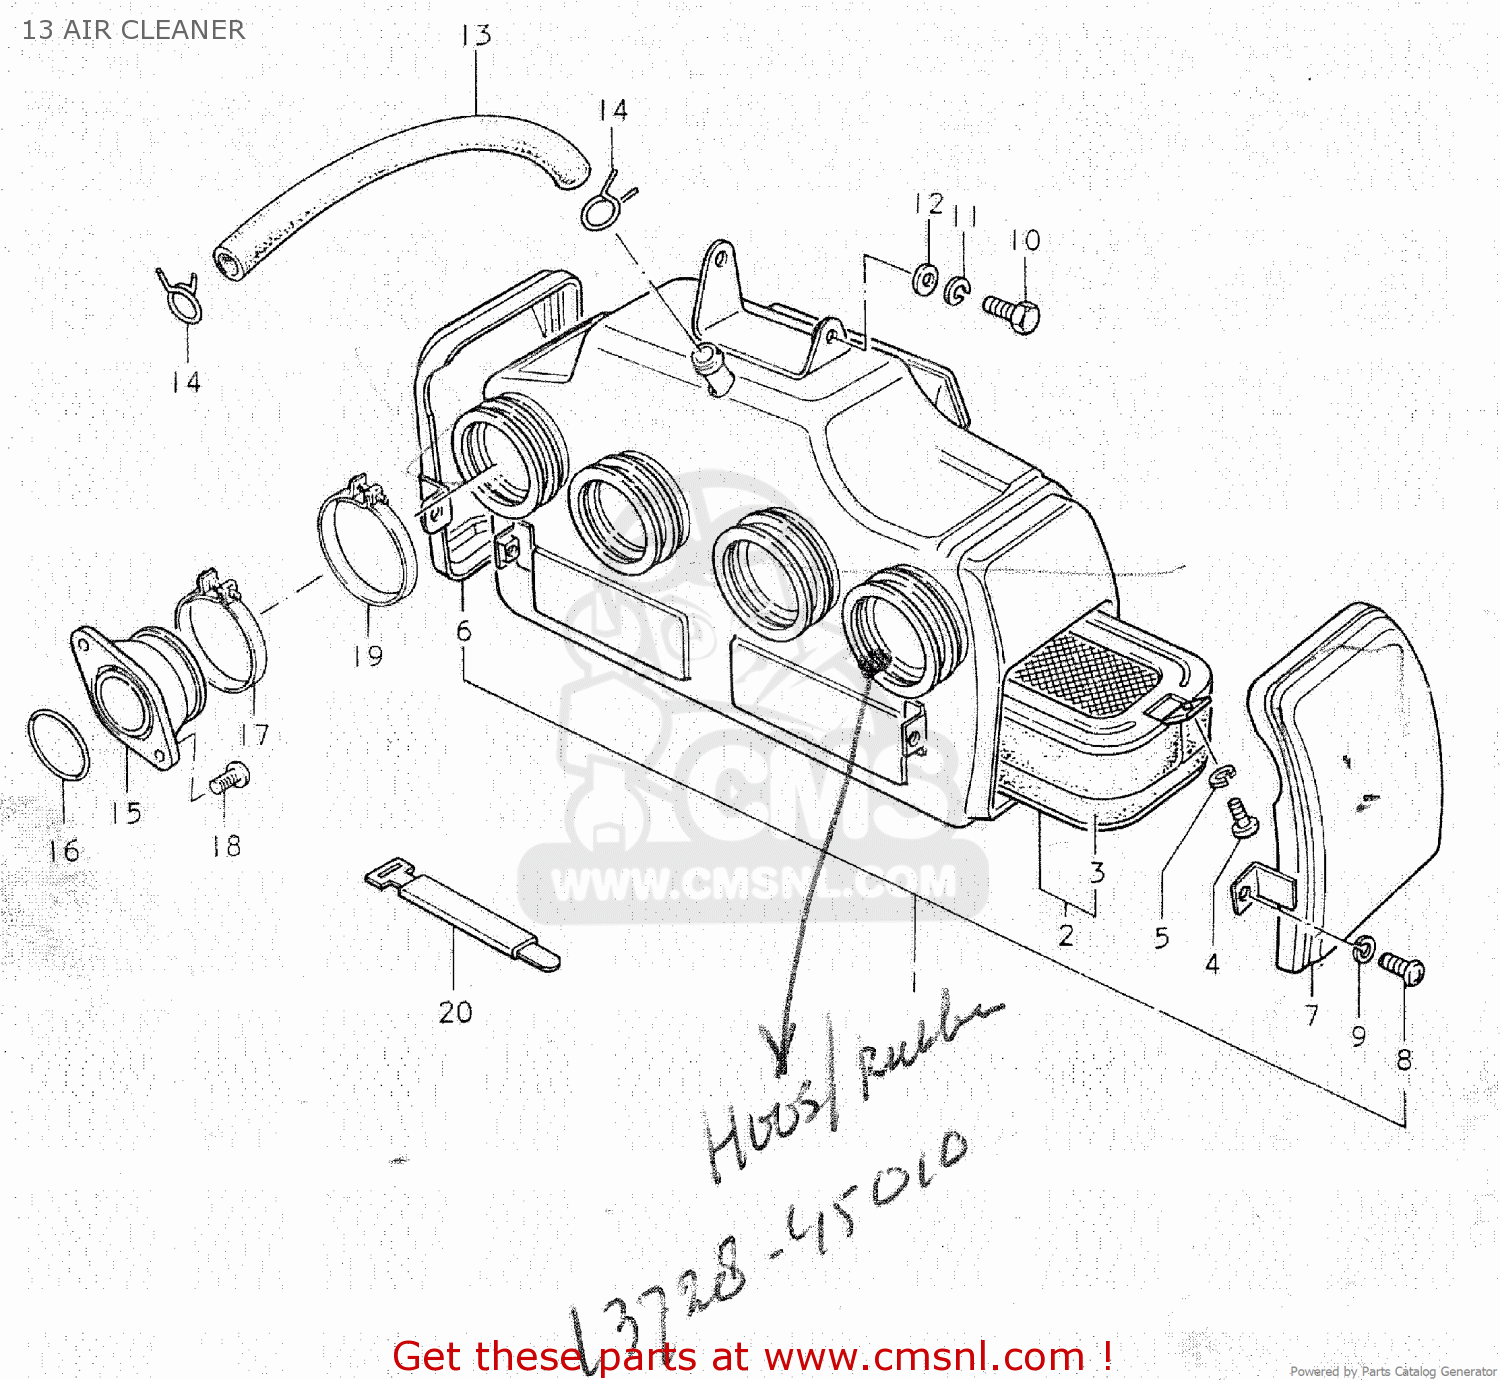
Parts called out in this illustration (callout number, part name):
1	CLEANER ASSEMBLY,AIR
2	FILTER ASSY,AIR CLEANER
3	FILTER
4	SCREW
5	LOCK WASHER
6	CAP,AIR CLEANER
7	COVER,AIR CLEANER,LEFT
8	SCREW
9	LOCK WASHER
10	BOLT
11	LOCK WASHER
12	WASHER
13	HOSE
14	CLIP
15	PIPE,INTAKE
16	O RING(D:2.4,ID:31.7)
17	CLAMP
18	SCREW
19	CLAMP
20	CLAMP(L:120)
